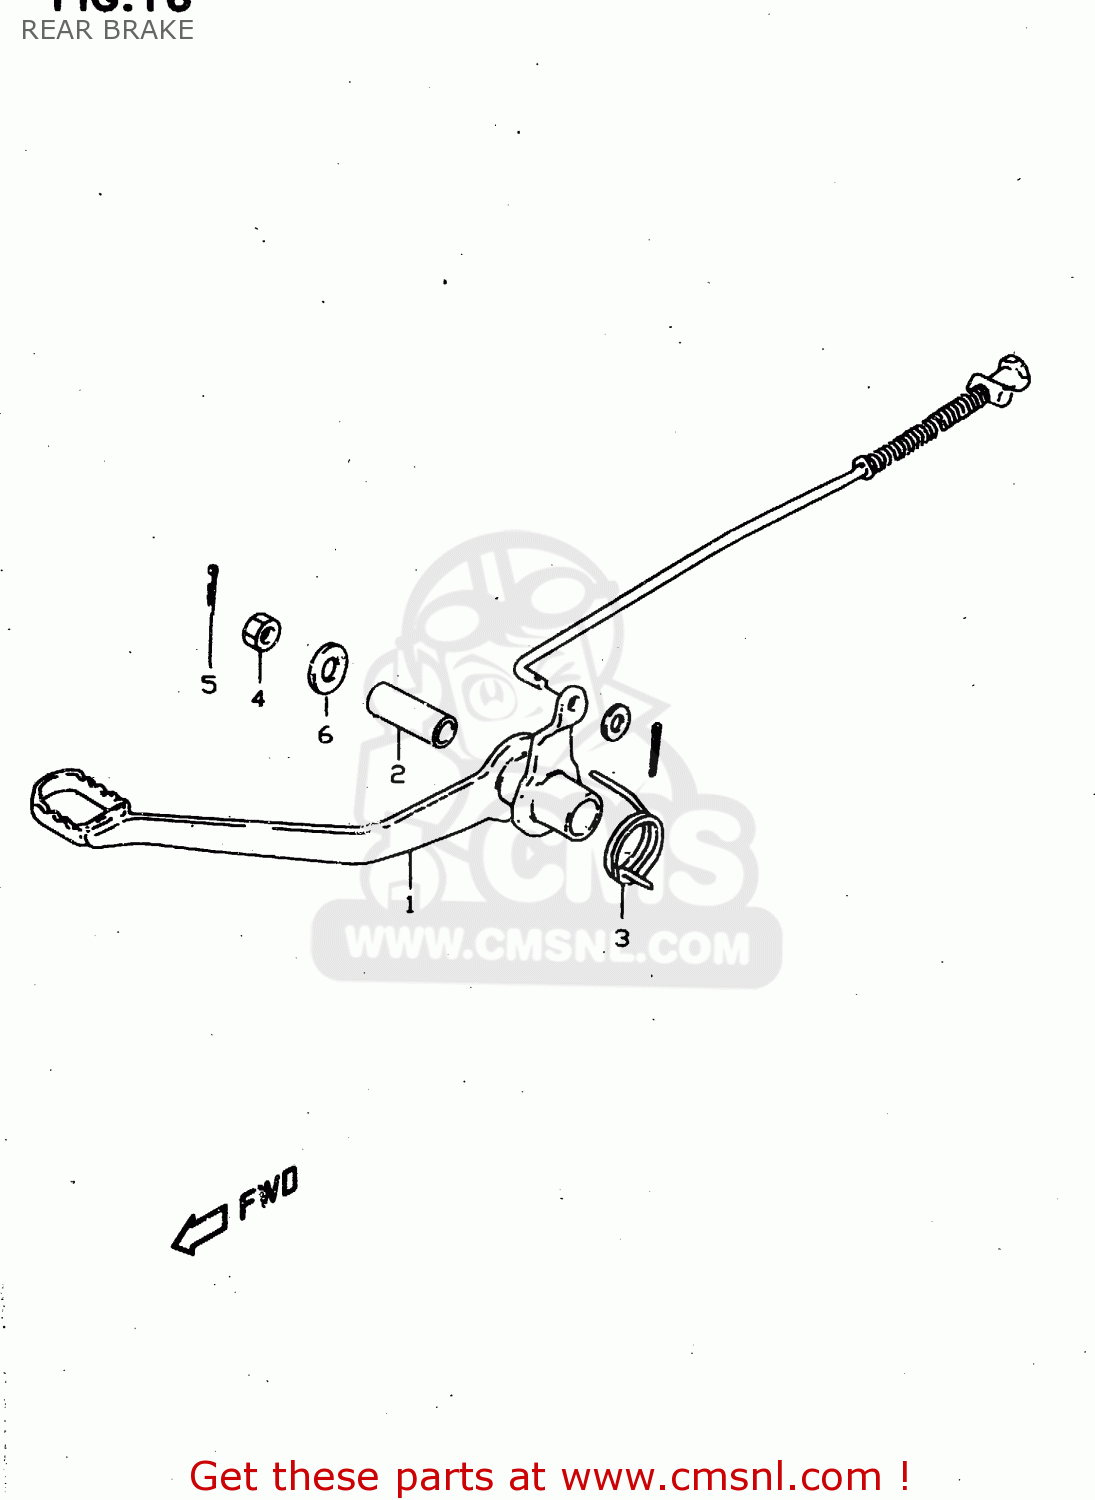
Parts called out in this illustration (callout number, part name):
1	PEDAL,BRAKE
2	SPACER,BRAKE PEDAL
3	SPRING,BRAKE PEDAL RETURN
4	NUT
5	PIN 25X20
6	WASHER(10.5X22X1.6)
